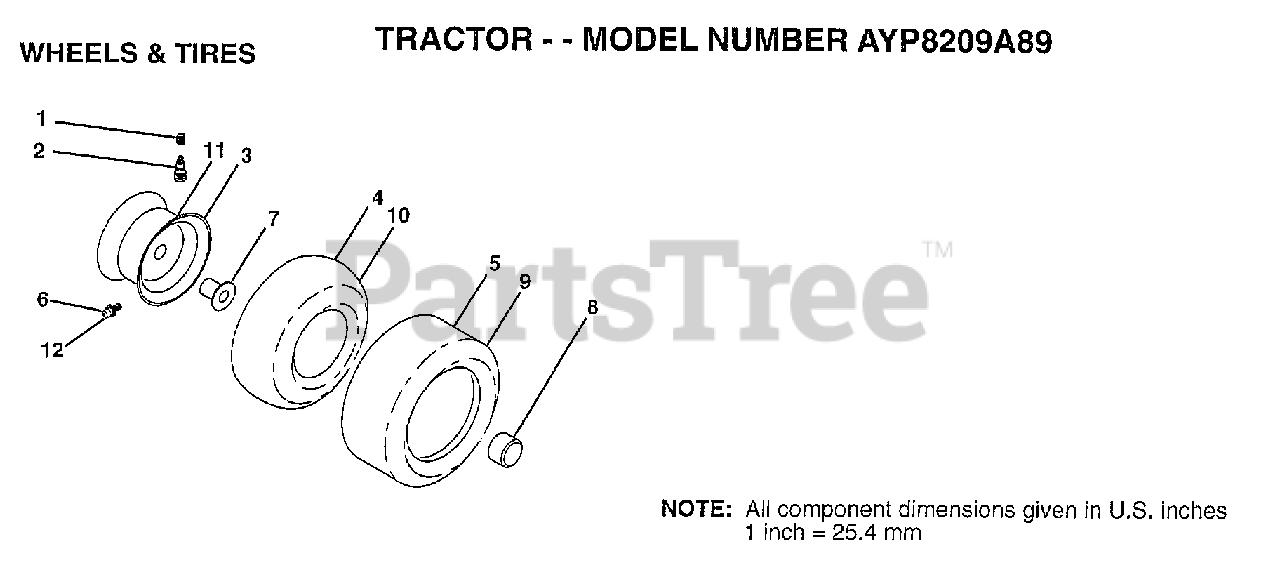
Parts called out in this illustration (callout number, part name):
1	VALVE CAP
2	VALVE STEM LT
3	"RIM ASM 8"" FRT"
4	TUBE.16X6.5/7.5-8
6	FITTING LT
7	"FLANGE, BEARING"
8	HUB CAP
10	TUBE.23X8/10-12
11	"RIM ASM 12"" REAR"
12	ZERK FITTING M
